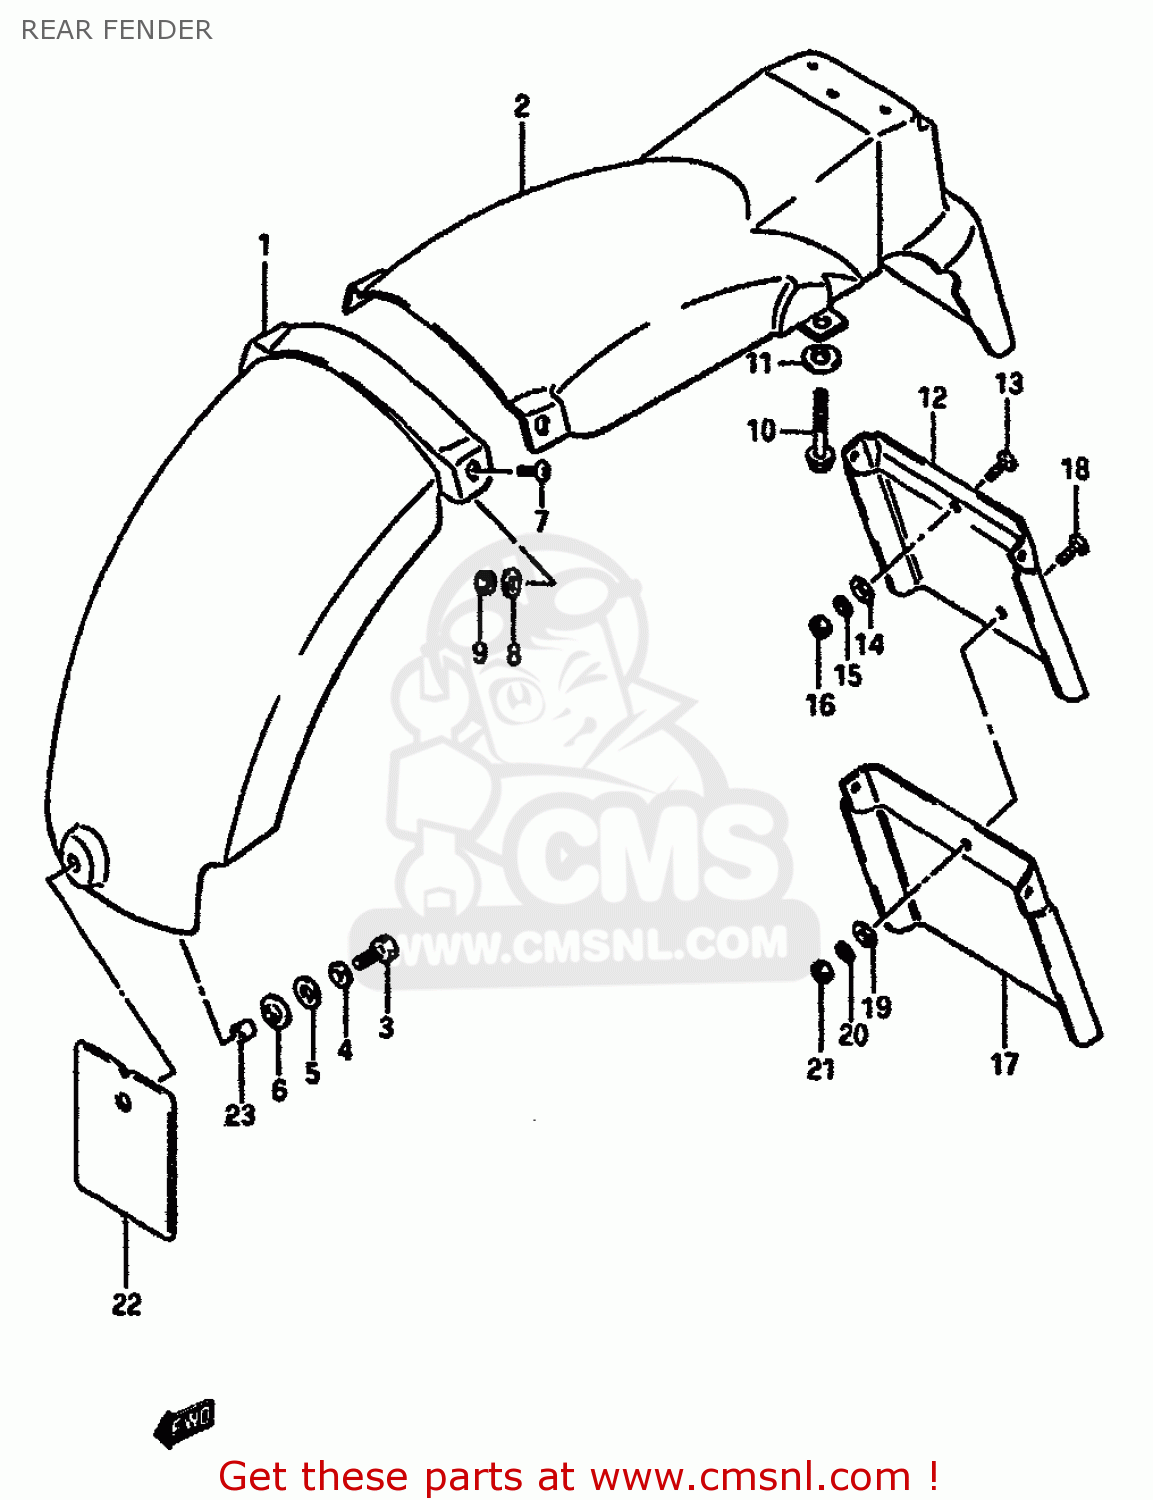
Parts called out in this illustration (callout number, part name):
1	BODY,REAR FENDER,FRONT
2	FENDER,REAR
3	BOLT
4	WASHER,LOCK
5	WASHER
6	WASHER
7	SCREW
8	WASHER
9	NUT 6MM
10	BOLT
11	WASHER
12	EXTENSION
13	SCREW 6X12
14	WASHER
15	WASHER,LOCK
16	NUT
17	MUD GUARD
18	SCREW
19	WASHER(6.5X16X1.2)
20	WASHER,LOCK
21	NUT
22	MUD GUARD,REAR FENDER,FRONT
23	SPACER (6.8X10X10)
